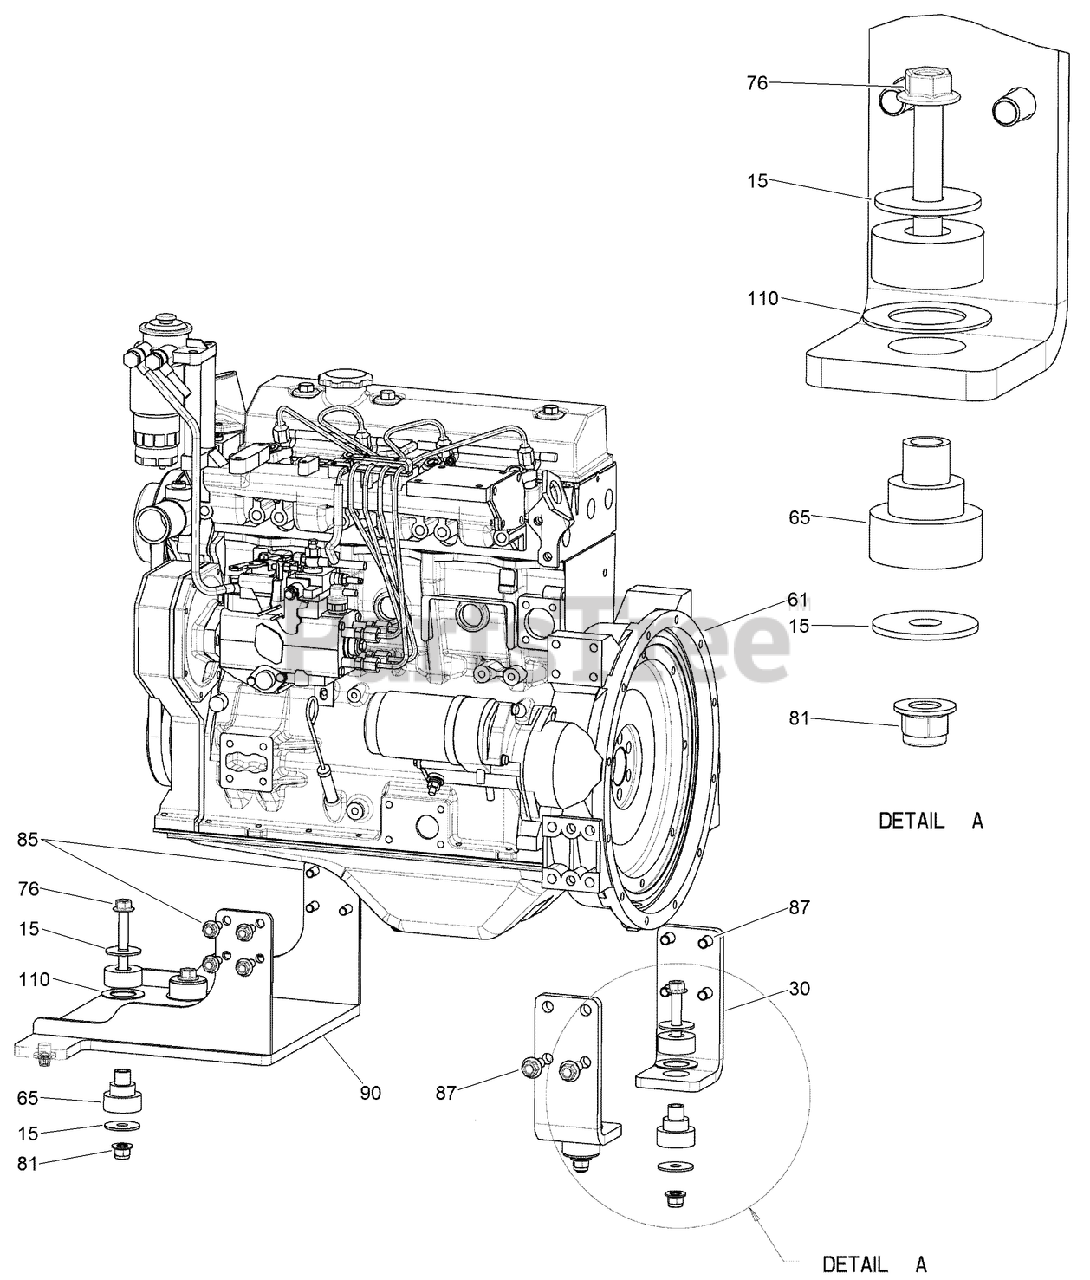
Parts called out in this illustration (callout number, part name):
15	WASHER-0.531 x 1.750 x 0.100 in CST ZND
30	MOUNT - Engine, Rear
65	ISOLATOR-MOUNTING, UNIVERSAL
76	SCREW-HHF
81	NUT-HHF, LOCK
85	SCREW-FLANGE
87	SCREW, METRIC FLANGE w/BODY-M12 x 30
90	ASSEMBLY - Engine/Radiator Mount
110	SPACER-ISOLATOR
